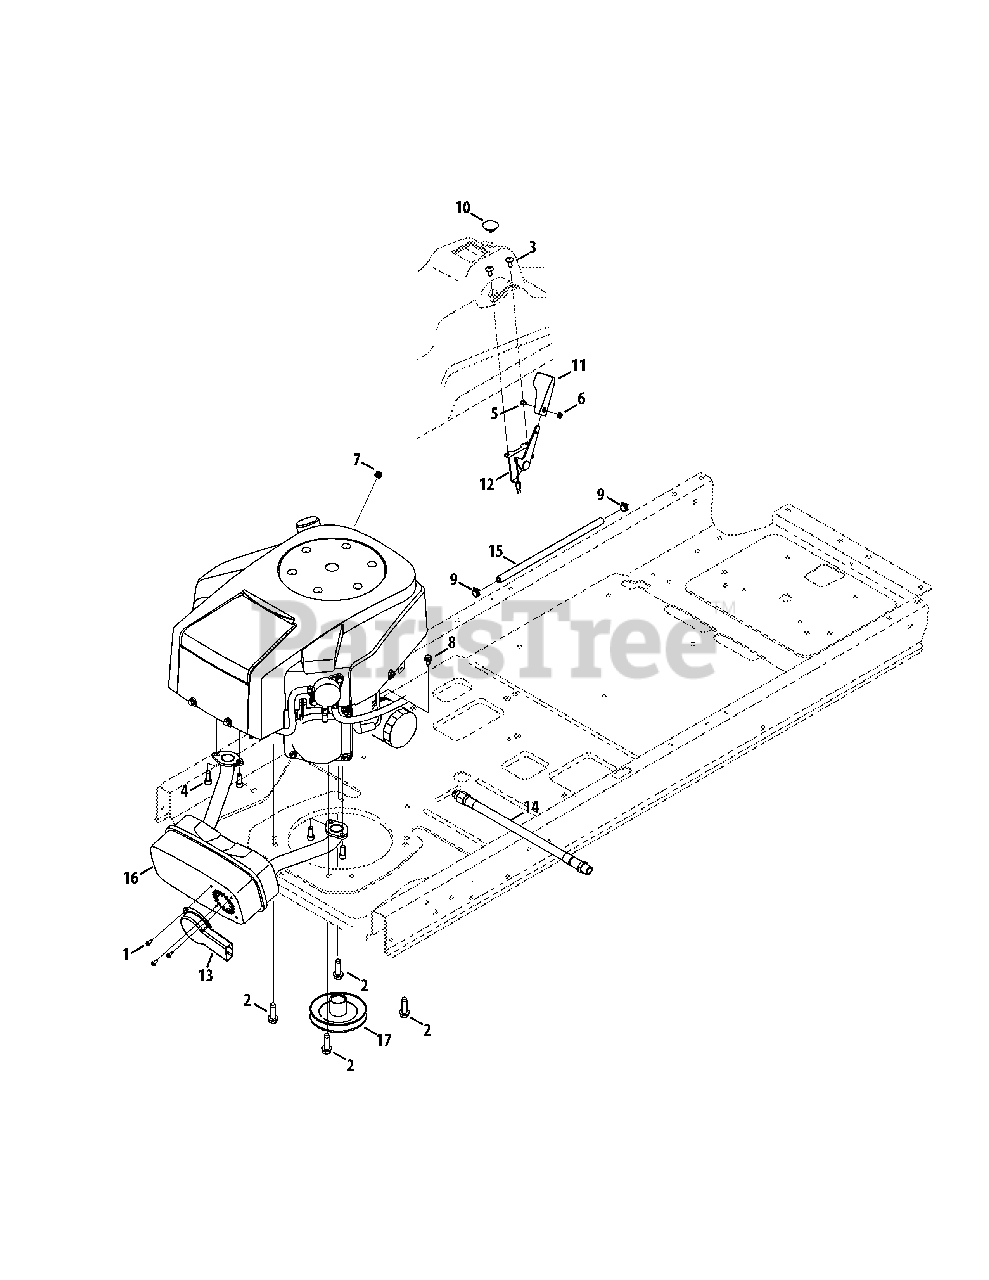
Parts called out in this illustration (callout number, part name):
1	Hex Washer Screw, #8-18 x .500
2	Hex Washer Screw, 3/8-16 x 1.00
3	Screw, 1/4-20 x .50
4	Socket Head Screw, 5/16-18 x .750
5	Screw, #8-32 x .375
6	Hex Nut, #8-32
7	Flange Lock Nut, 1/4-20
8	Hex Washer Screw, 1/4-20 x .625
9	Hose Clamp, .490 Dia.
10	Choke Plug
11	Throttle Control Knob
12	Throttle/Choke Control Cable
13	Muffler Deflector Long
14	Oil Drain Hose
15	Fuel Hose, 1/4
16	Twin Muffler
17	Engine Pulley
